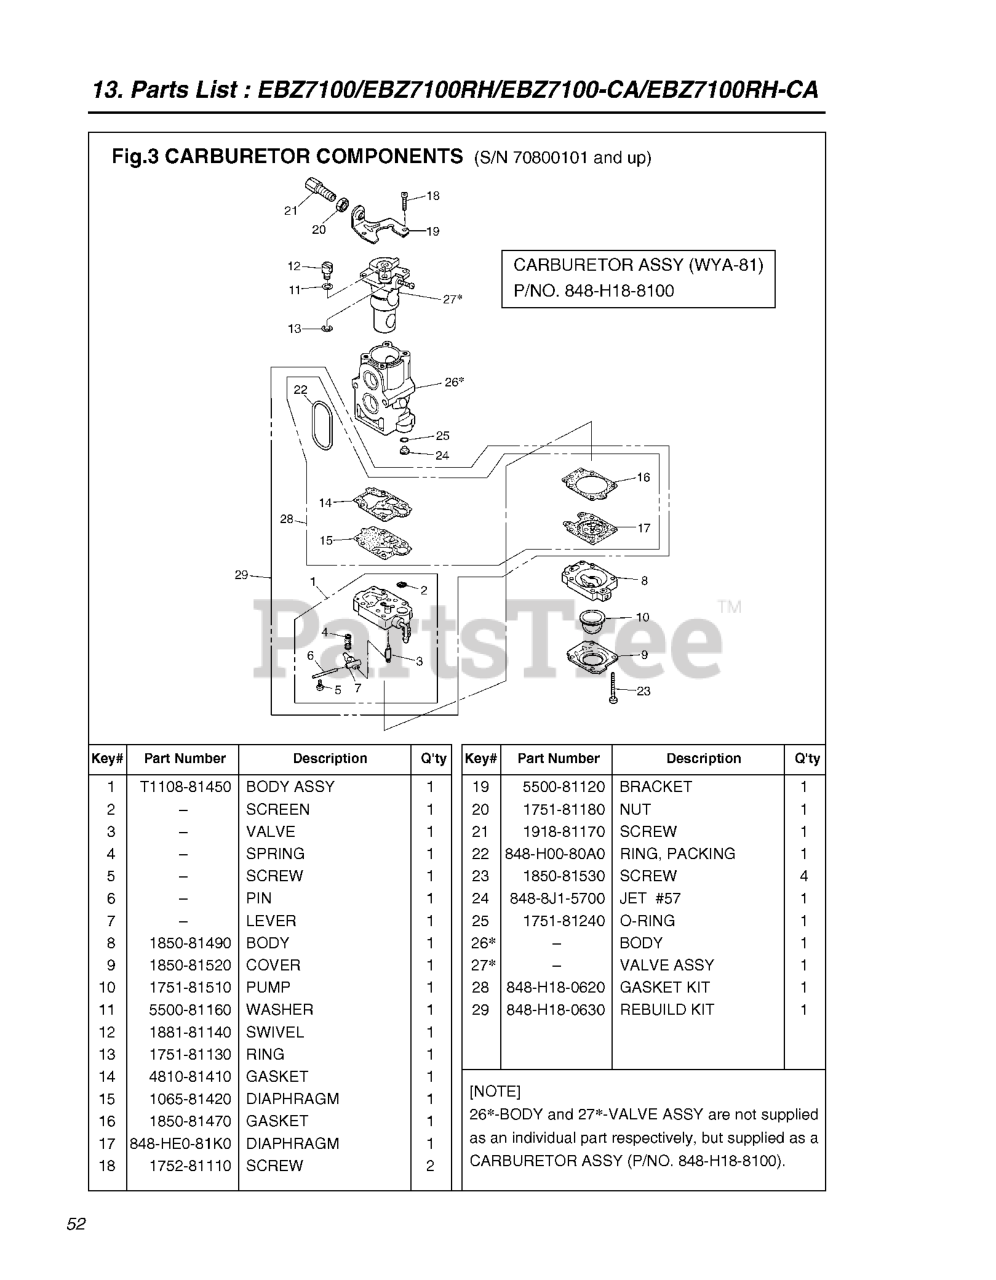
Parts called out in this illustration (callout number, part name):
1	BODY-A-PUMP
9	1OVER
11	WASHER
12	SWIVEL
13	RING
15	DIAPHRAGM
17	DIAPHRAGM
18	SCREW
19	BRACKET
20	NUT
21	ADJUSTER
22	RING
26	CARBURETOR ASSY
27	CARBURETOR ASSY
28	GASKET KIT
29	REBUILD KIT
